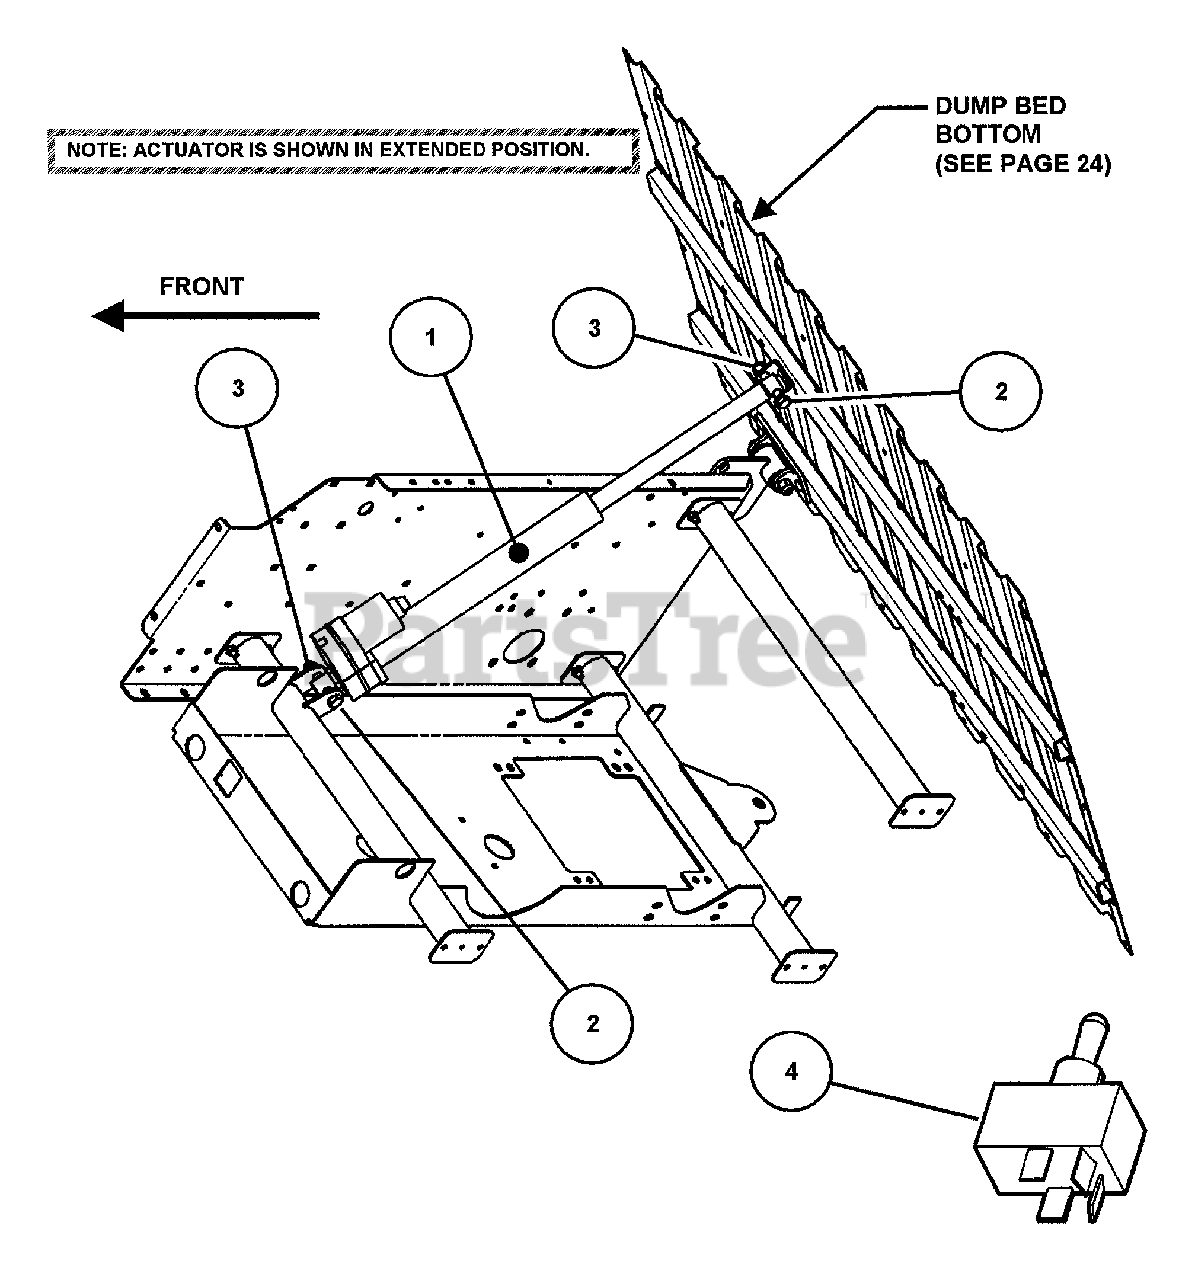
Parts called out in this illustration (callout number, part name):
1	LINEAR ACTUATOR
2	HHCS, 1/2-13 X 3 YZ
3	HNYL, 1/2-13 YZ REGULAR
4	SWITCH, SELF CENTERING, DECK LIFT
